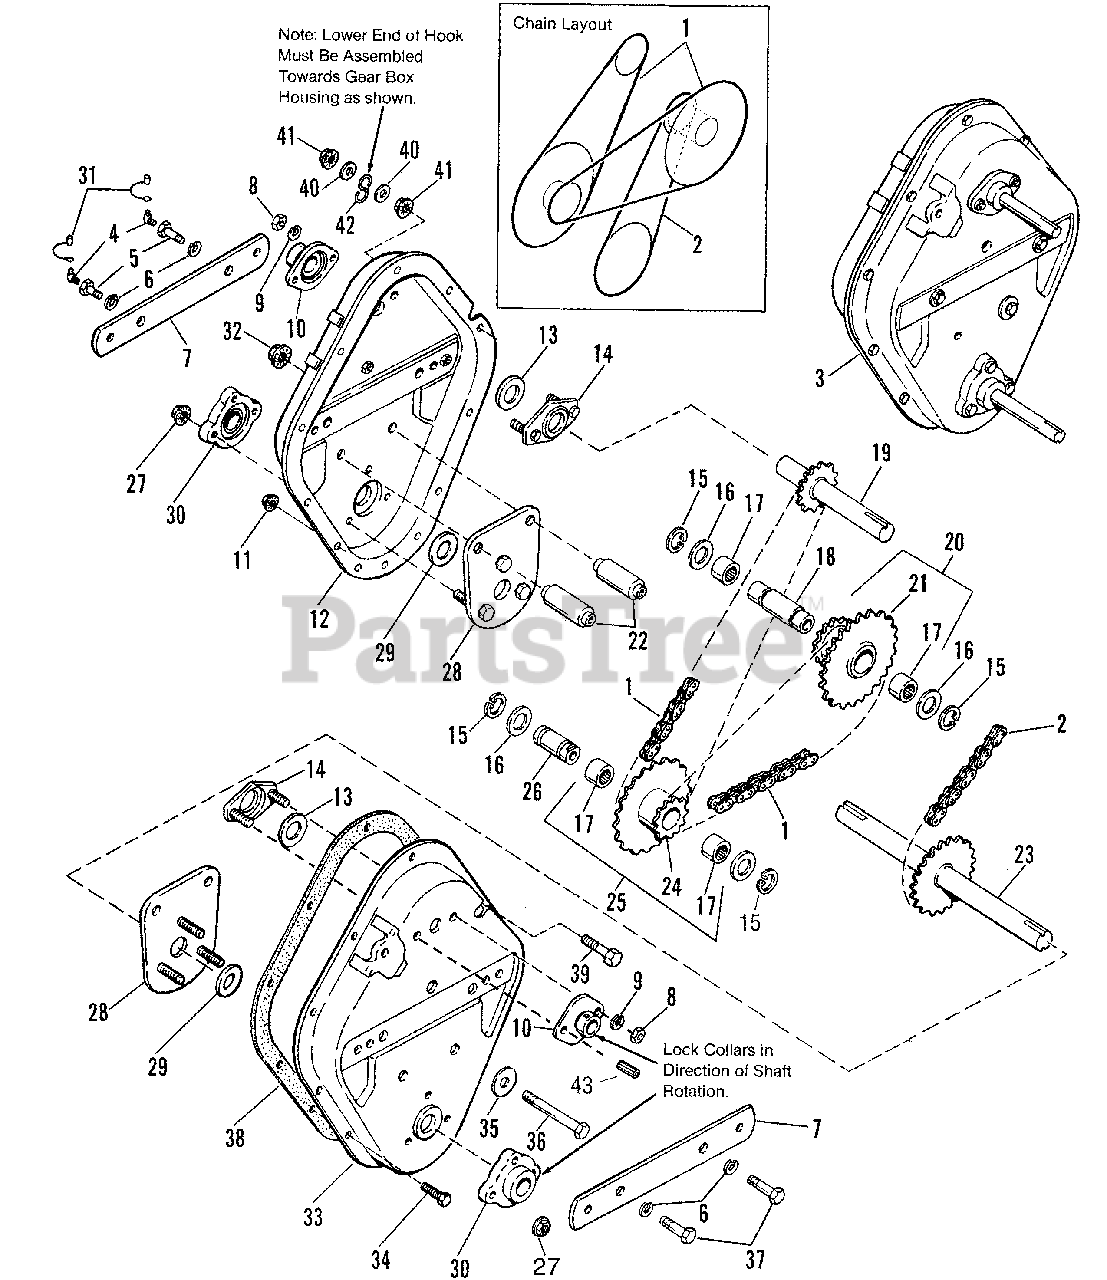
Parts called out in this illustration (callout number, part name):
1	CHAIN, # 40
2	CHAIN, # 50
3	TRANSMISSION SUB ASSEMBLY (Incl. Ref. Nos. 1-16, 18-38 on this page) & Incls. Ref. Nos. 1-5,7,11,17,18,19,34,36 & 38 in the 36" Tiller Drive Group)
4	FITTING, Grease
5	BOLT, Hex Head, Drilled & Tapped
6	LOCKWASHER, 1/2
7	BAR, Side
8	NUT, Hex, 5/16-1
9	LOCKWASHER, 5/16
10	BEARING
11	LOCKNUT, 5/16-18
12	CASE ASSEMBLY, Half, R.H.
13	SEAL
14	PLATE ASSEMBLY, Upper Bearing
15	RING, Retaining
16	WASHER, 1
17	BEARING, Roller
18	SPACER, Inter.
19	SHAFT ASSEMBLY, Pulley
20	SPROCKET & BEARING ASSEMBLY, (Incl. Ref. Nos. 17 & 21)
22	SPACER
23	SHAFT ASSEMBLY, Tine
25	SPROCKET & BEARING ASSEMBLY, (Incl. Ref. Nos. 17 & 24)
26	SPACER, Internal
27	LOCKNUT, Hex, Jam, 3/8-16
28	PLATE ASSEMBLY
29	SEAL
30	BEARING
31	CAP, Grease
32	LOCKNUT, Flange, 1/2-13
33	CASE ASSEMBLY, Half, L.H.
34	CAPSCREW, Hex Head, 5/16-18 x 5/8
35	WASHER, 1/2
36	CAPSCREW, Hex Head, 1/2-13 x 4
37	CAPSCREW, Hex Head, 1/2-20 x 1
38	GASKET
39	CAPSCREW, Hex Head, 5/16-1 8 x 1-1 /4
40	WASHER, 3/8
41	LOCKNUT, Flange, 5/16-18
42	HOOK, "S"
43	ANCHOR SPRING
